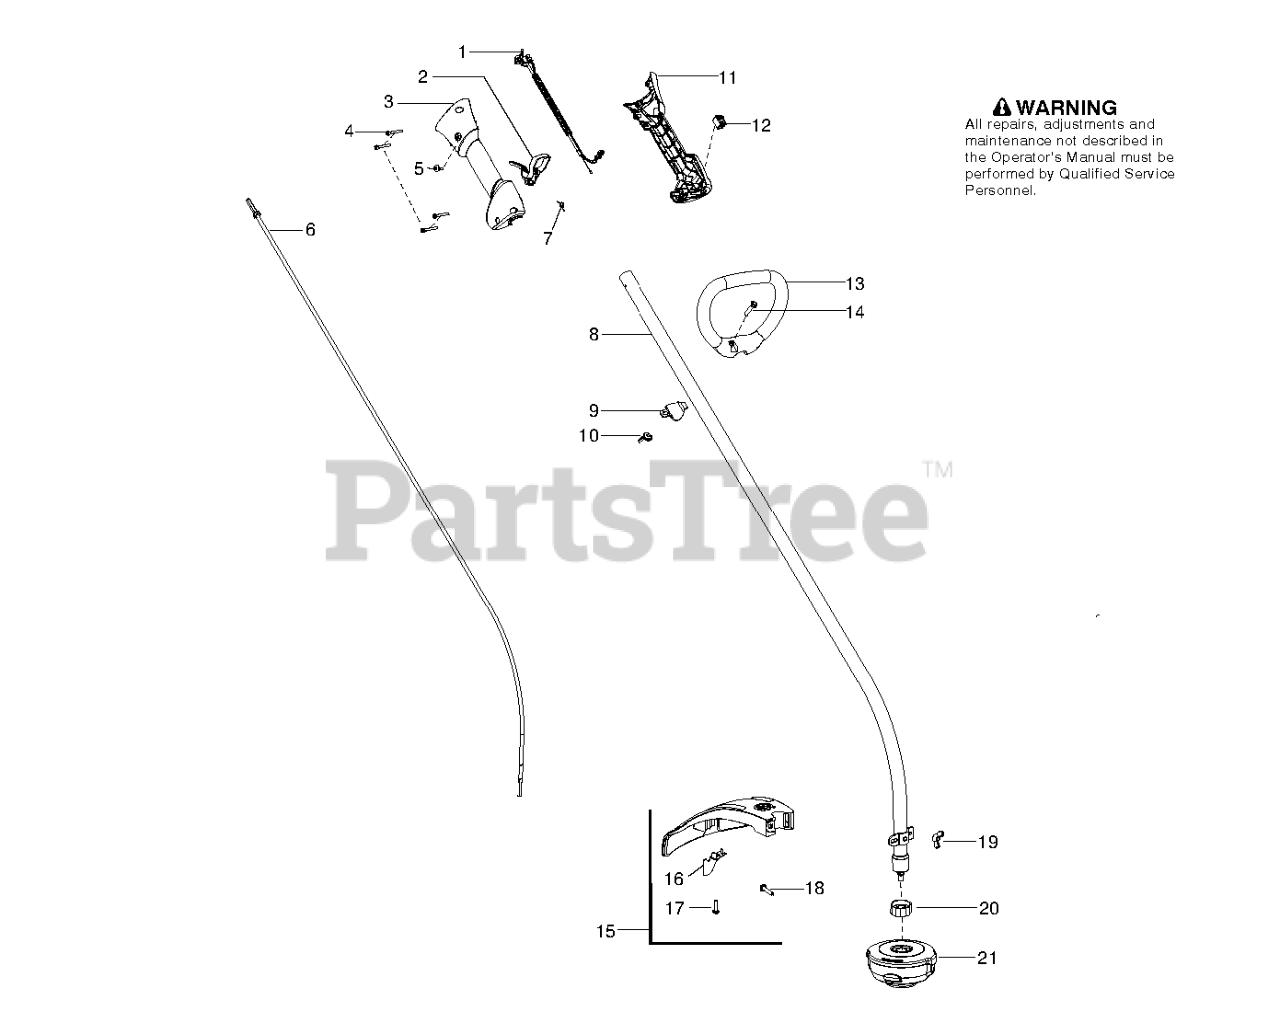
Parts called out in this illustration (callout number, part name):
1	ASSY CABLE / WIRE HARNESS
2	TRIGGER THROTTLE HVA ORANGE
3	HSG THROTTLE RIGHT NL HVA
4	SCREW M4 X 1.75 PT 16MM
5	SCREW-10-14 X 1/2 PLASTITE
6	FLEX SHAFT 52"
7	SPRING TRIGGER
8	KIT DRIVE SHAFT
8	KIT DRIVESHAFT
9	CLAMP ASSIST HANDLE
10	WINGNUT, TYPE 2
11	HSG THROTTLE LEFT HVA
12	SWITCH
14	BOLT, TYPE 2
15	TRIMMER GUARD 128C
15	SHIELD ASSY
16	KIT - LIMITER - LINE
18	BOLT, TYPE 2
19	NUT-"D" HANDLE
19	NUT
21	T25 TRIM HEAD RH
